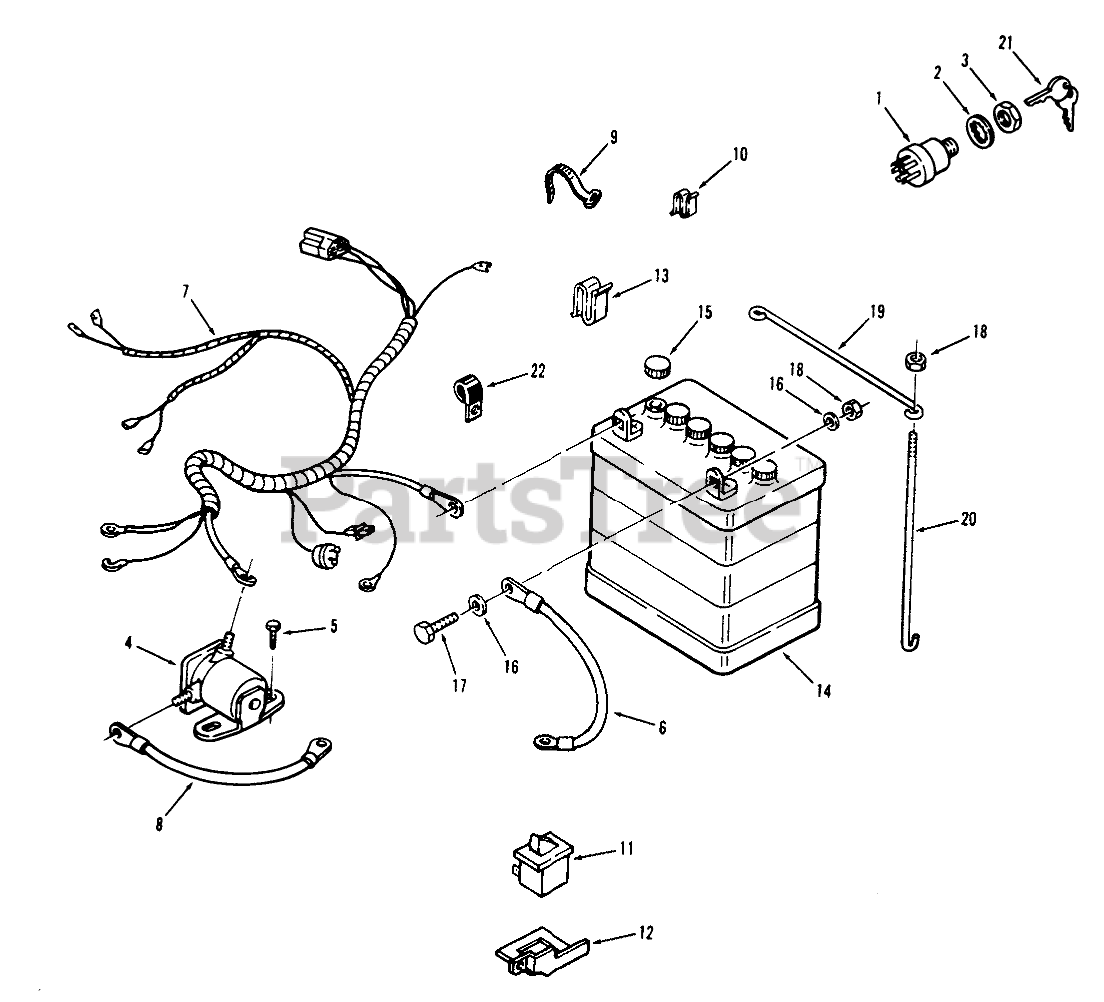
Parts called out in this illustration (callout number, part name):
1	ASSY-SWITCH IGNITION
2	LOCKWASHER
4	Solenoid
5	Bolt
6	Ground Wire
7	Wire Harness
8	Wire
9	PLASTIC TIE
10	SPEED CLIP
11	SWITCH INTERLOCK
12	Bracket-Switch
13	CLIP
14	Battery
17	Bolt
18	Nut
19	ROD-HOLD DOWN
20	Hook
21	Key-EL
22	Clamp
